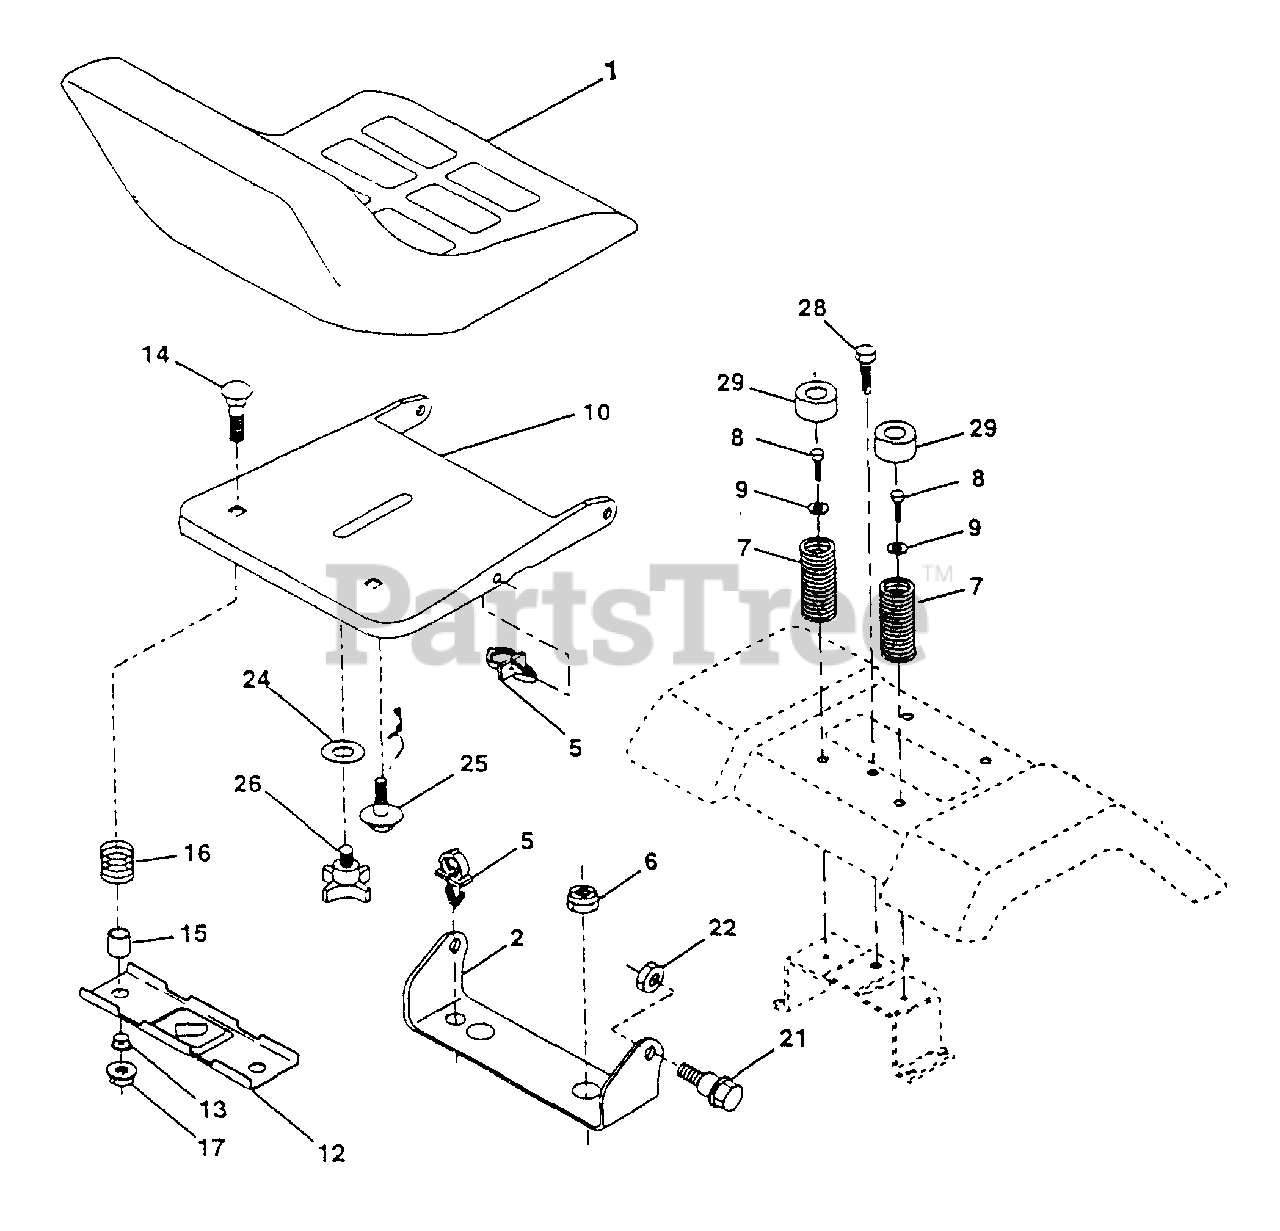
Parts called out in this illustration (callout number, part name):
1	Seat V-550 Gry/blk Std
2	Bracket Pivot Seat 8 720
5	Clip Push-in .375 x .250
6	Nut Crownlock 3/8-16 Unc
7	Spring Seat Cprsn 2 250 Blk Zi
8	Screw Hwsh Thdrol 5/16-18 x 1/2
9	Washer 13/32 X 1 X 14 Ga
10	Pan Seat
12	Bracket Mounting Switch
13	Bushing Snap Blk Nyl 50 Id
14	Bolt Rdhd Sht Nk 1/4-20x1-3/8
15	Spacer Split 28x 88 Yel Zinc
16	Spring Cprsn 1 310 Blk Pnt
17	Nut Lock 1/4 Lge Flg Gr 5 Zinc
21	Bolt Shoulder 5/16-18 Unc Blkz
22	Nut Crown Lock 5/16-18
24	Washer 17/32 X 1-3/16 X 12 Ga
25	Bolt Shoulder 5/16-18 X 62
26	Knob Seat 1/2-13unc Blk
28	Screw Thdrol 3/8 - 16 x 112 Ty-TT
29	Cap Spring Seat
